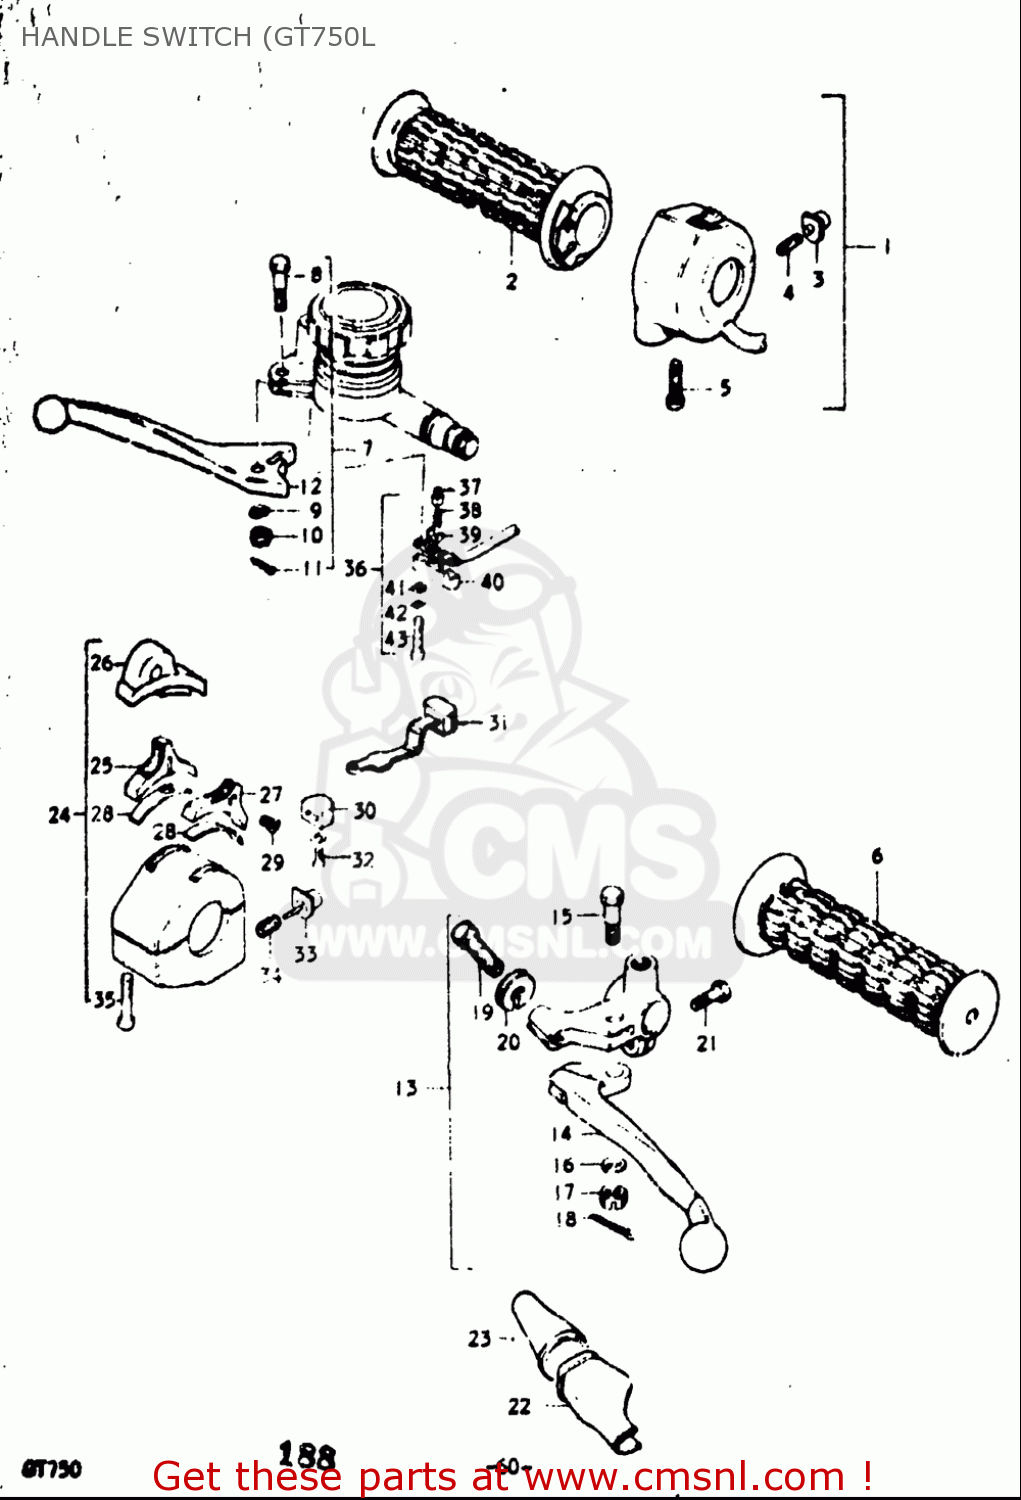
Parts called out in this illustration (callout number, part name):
1	GRIP ASSY,THROTTLE
2	GRIP,THROTTLE
3	BUTTON
4	SPRING
5	SCREW
6	GRIP
8	BOLT
9	WASHER,LOCK
10	NUT,LEVER FITTNG
11	PIN 16X20
12	LEVER,BRAKE
13	LEVER ASSY,CLUTCH
14	LEVER,CLUTCH
15	BOLT,LEVER PIVOT
16	WASHER,LOCK
17	NUT,LEVER FITTNG
18	PIN 16X20
19	ADJUSTER,CABLE
20	NUT,CABLE ADJUSTER
21	BOLT
22	COVER,CLUTCH LEVER
23	BOOT,CLUTCH CABLE
25	KNOB,HANDLE SWITCH
27	KNOB
28	PLATE,SWITCH KNOB
29	SCREW
32	SCREW
33	BUTTON,HORN
34	SPRING,BUTTON
35	SCREW
36	SWITCH ASSY,STOP
37	CONTACT,SWITCH
38	CONTACT,SWITCH
39	CONTACT,SWITCH
40	COVER,FR BK TERMINAL BASE
41	WASHER
42	WASHER,LOCK
43	SCREW
